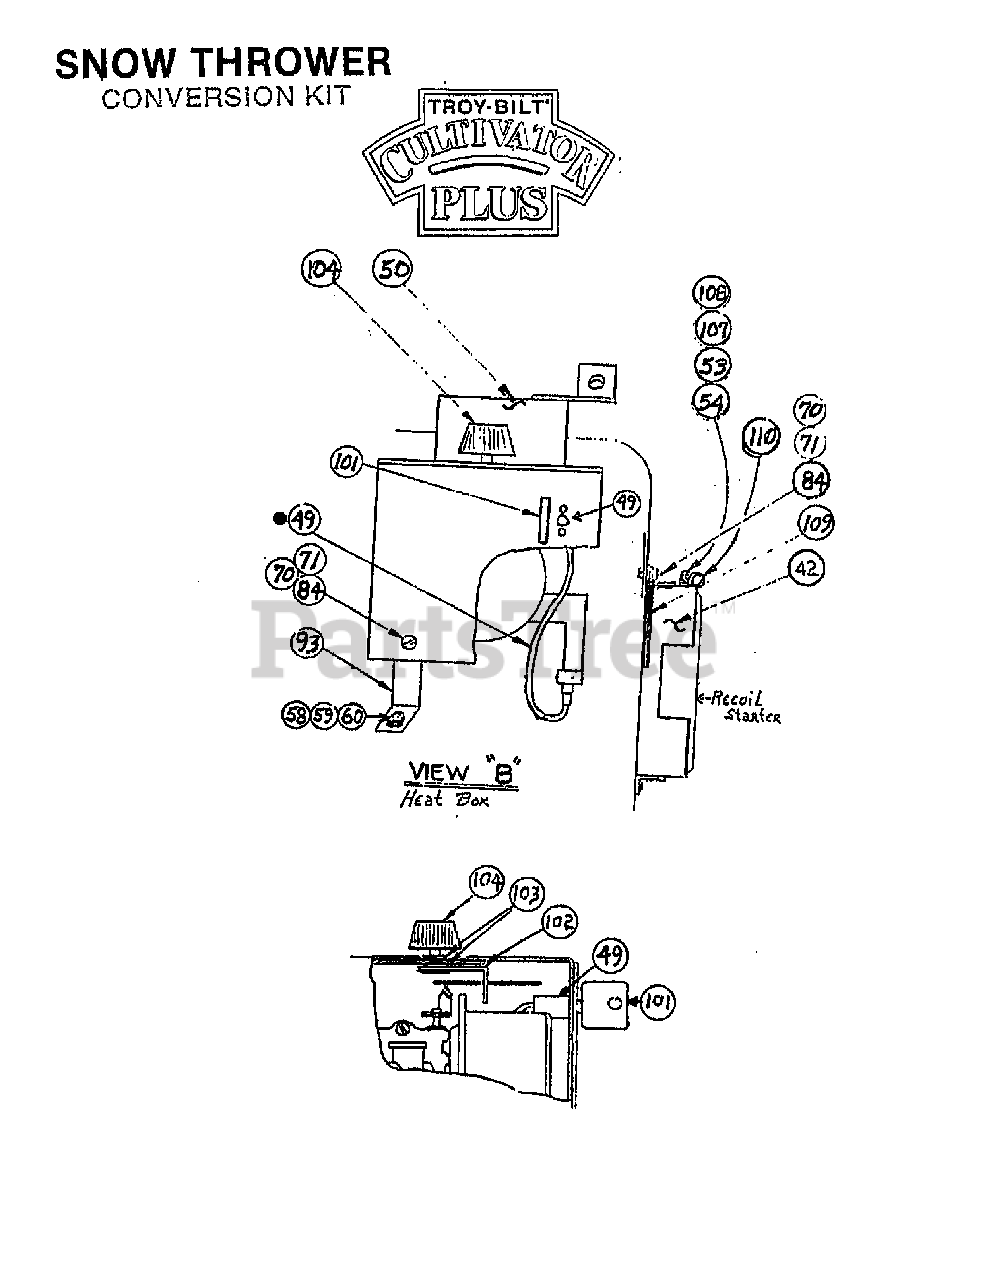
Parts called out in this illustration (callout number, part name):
3	WRAP SHEET W/DECALS
4	DEFLECTOR-VANE
5	MAIN GUARD W/DECAL
6	ASSM-SIDE PLATE LH
7	ASSM-PLATE RH
9	GUARD-DRIVE W/DECAL
10	BELT-V UPR DR SNOWBLOW
11	BELT-AUGER
12	BRKT-LOCKING PNT
13	DEFLECTOR-ROD WELD
15	SHAFT PICK-UP
16	BRKT-MOUNTING
18	PULLEY-ENGINE PICK-UP
19	PULLEY-AUGER DRIVE
20	SHIELD-WEATHER
21	ASSM-PIVOT VANE
22	ROD-LINKAGE
23	BRKT-MOUNTING WELD
24	HOLDER-IDLER WELD
25	PULLEY-IDLER
26	ASSM-IDLER PLATE
27	PLATE-MOUNTING
28	HANDLE-VANE CONTROL
29	GRIP-VANE CONTROL
30	PULLEY-ENGINE 4L
31	SPRING-COMPRESSION
32	ASSM-IDLER PULLEY
33	BUSHING-PIVOT
34	PULLEY-AUGER
35	STOP-OVERCENTER
36	GUIDE-BELT
38	ASSM-IDLER ARM
39	SPRING-AUGER STOP
42	ASSM-RECOIL GUARD
43	PLATE-AUGER
46	SUPPORT-AUGER
47	ASSM-BEARING
49	ASSM-SWITCH
50	COVER-CARB W/DECAL
51	D SPACER-IDLER
52	BOLT
53	WASHER
54	NUT
55	BOLT
56	WASHER
57	WASHER
58	BOLT
59	WASHER
60	NUT
61	WASHER
63	SCR-HH 5/16-18 X .20 STH ZP
64	BOLT
65	WASHER
66	NUT
67	RING-SNAP
68	WASHER-FLAT 3/4
69	SCR-RD HD #10-24 X 3/4
70	WASHER
71	NUT
72	SCR-HH 1/4-20 X 6
75	SCR-HEX TYPE A #10-.500
76	BOLT-HH 1/4-28 X 3/4
77	WASHER-1.06 X .25 X .067
78	KEY-WOODRUFF 1/8 X 1/2
79	BOLT
80	NUT
81	NUT
83	SCR-SHAKE PR 1/4-15 X 3/4
84	SCR-RH M10-24 X .50 ZP
86	CUSHION-6.74 5 LONG
87	CUSHION-3.75 LONG
88	KEY
89	PIN-HITCH ZP
90	KEY-.188 SQ X 1.25
91	SCR-HEX SOC FL #10-24
92	NUT
93	BRACE-SUPPORT
94	SCR-RD HD #8-32 X 5/8
95	NUT-LOCK #8-32
96	NUT
97	SCR-FLT HD 5/16-24
98	BOLT
99	PIN
102	LEVER-REMOTE CHOKE
103	WASHER
104	N KNOB-CHOKE LEVER
105	ENGINE STUD
106	SCR-HH 5/16-18X.63 G5
107	WASHER
110	CLAMP-CABLE
112	HINGE-SHROUD
113	WASHER
114	WASHER-FLAT 7/16 SAE
115	SCR-FLHH 5/16-24 X .75 ZP
117	DECAL-CARB COVER
118	DECAL-"CULTIVATOR-PLUS"
119	DECAL-WARN. BELT CVR
122	DECAL-DEFLECTOR PLT LT
123	DECAL-DEFLECTOR PLT RT
124	DECAL-ATTACH INST
126	DECAL-ANSI
